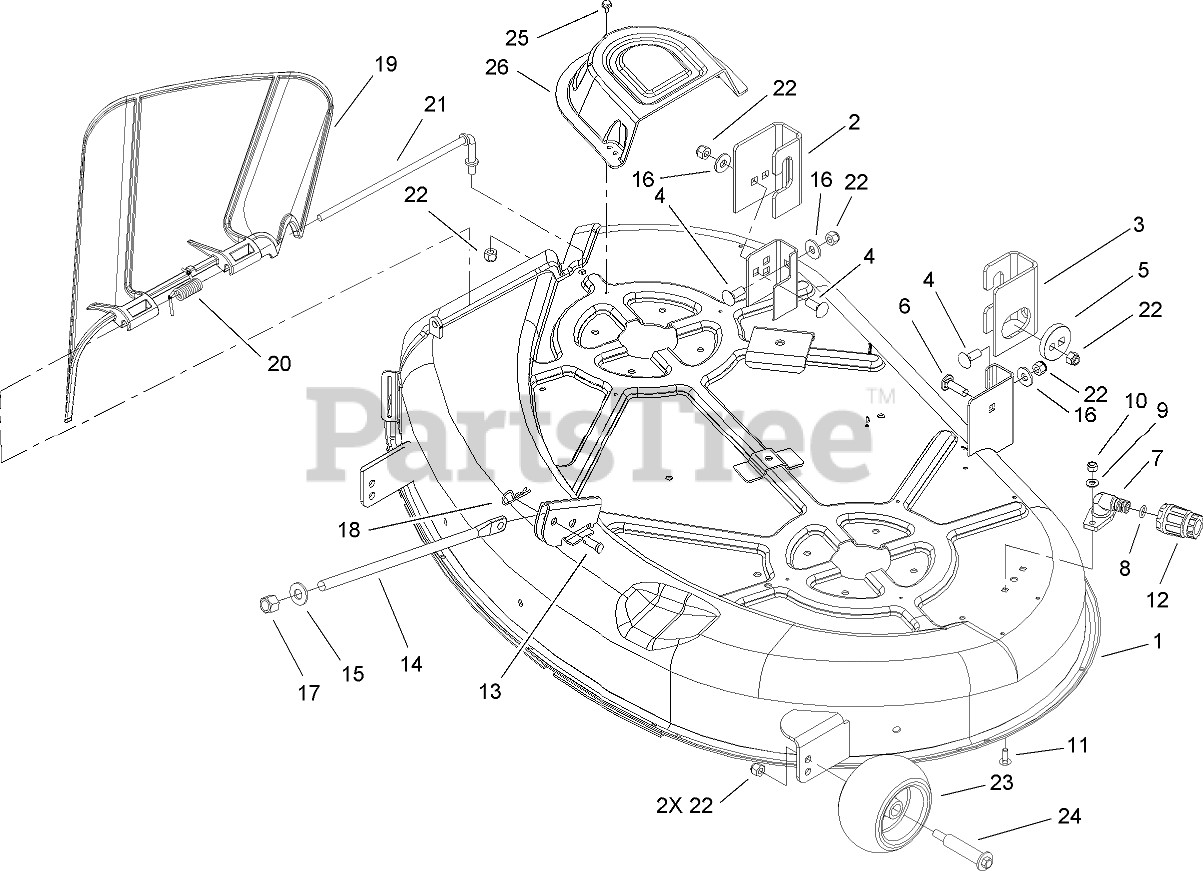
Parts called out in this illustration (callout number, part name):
1	42 INCH DECK ASM
2	BRACKET-HANGER, RIGHT REAR
3	BRACKET-HANGER, LEFT REAR
4	BOLT-CARR
5	ECCENTRIC
6	SCREW-CARR
7	FITTING-WASHOUT
8	O-RING
9	WASHER-FLAT
10	NUT-LOCK, NI
11	BOLT-CARR
12	CONNECTOR-HOSE
13	PIN-CLEVIS
14	ROD-LIFT
15	WASHER-THRUST
16	WASHER-HARDENED
17	NUT-LOCK, NI
18	PIN-HAIR
19	DEFLECTOR
20	SPRING-TORSION
21	ROD-PIVOT
22	NUT-LOCK, NI
23	ROLLER-SCALP, ANTI
24	BOLT-SHOULDER
25	SCREW-HWHTF
26	COVER-BELT
